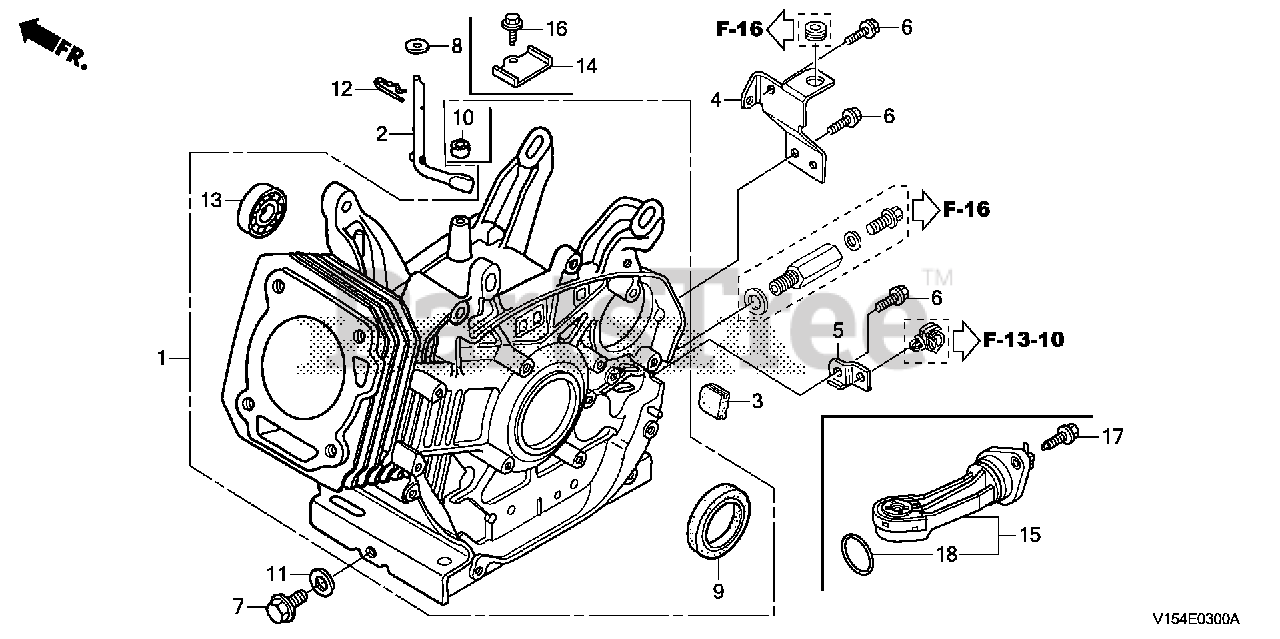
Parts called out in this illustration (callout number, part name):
1	CYLINDER ASSY. (SELF STARTER+ALERT)
3	GROMMET, WIRE
7	BOLT, DRAIN PLUG
9	OIL SEAL (35X52X8) (NOK)
11	WASHER, DRAIN PLUG (12MM)
13	BEARING, RADIAL BALL (6202) (FUJIKOSHI)
13	BEARING, RADIAL BALL (6202)
14	BRACKET A, HARNESS
15	SWITCH ASSY., OIL LEVEL
16	BOLT, FLANGE (6X12) (CT200)
17	BOLT, FLANGE (6X16)
18	O-RING (37.9X2.4)
